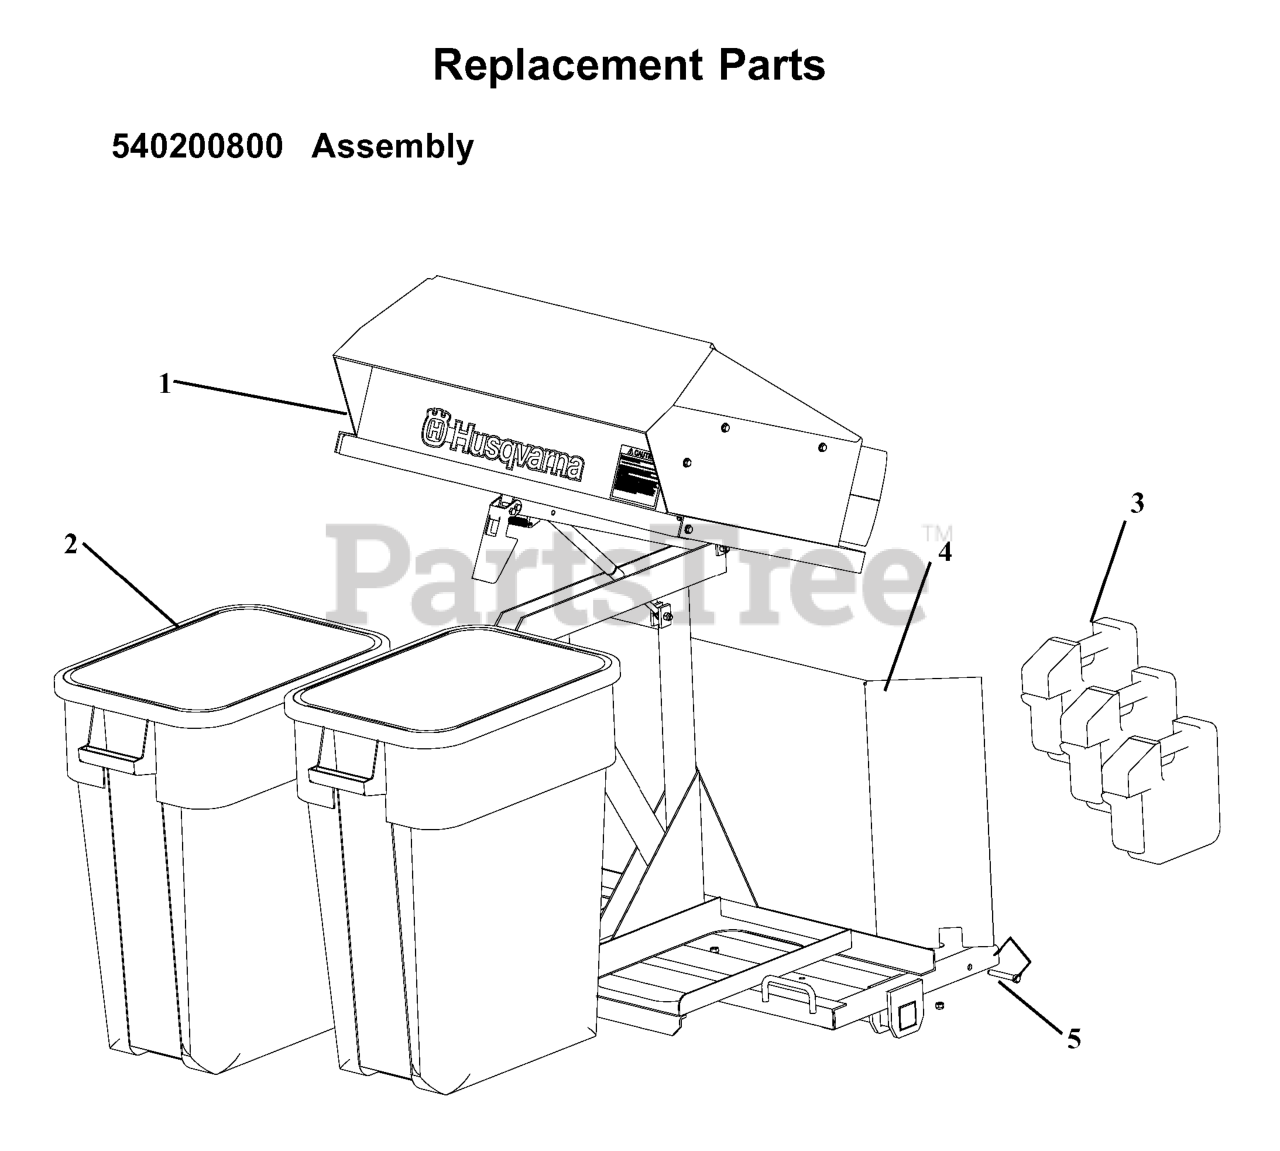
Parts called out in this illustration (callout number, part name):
1	FRAME/TOP ASSY
2	CONTAINER - 30 GAL/GREEN
3	FRONT WEIGHT PZ DFS
4	HEAT SHIELD
5	PIN-WIRE LOCK
